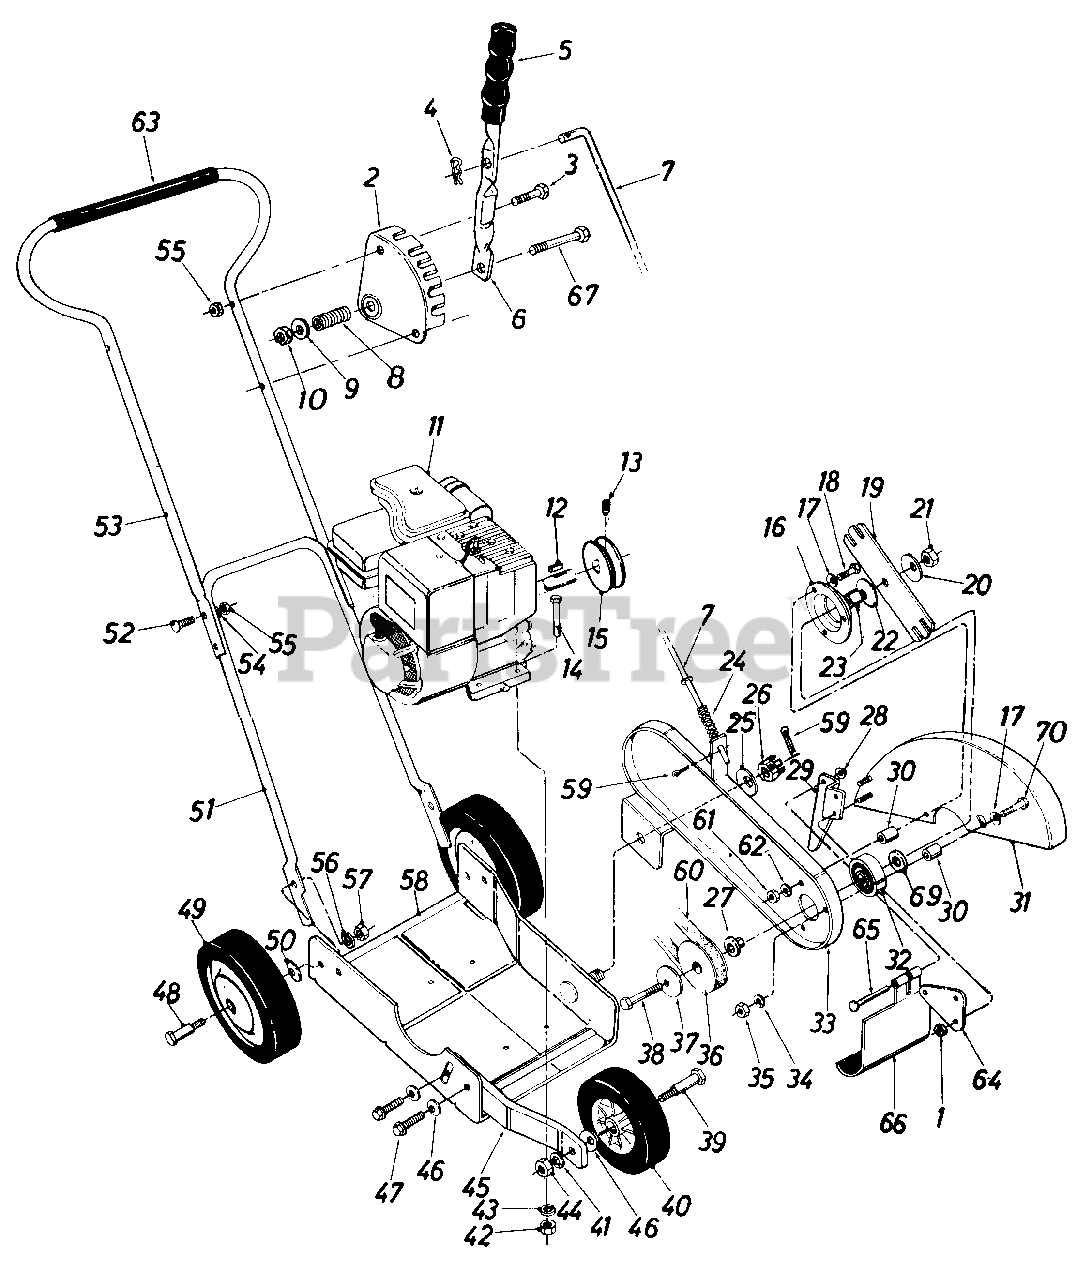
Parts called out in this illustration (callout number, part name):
1	Hex Cent. L. Nut 1/4-20 Thd .
3	Hex Bolt 1/4-20 x 1.25" Lg.
4	Cotter Pin 1/8" Dia. x 1.0" Lg.
5	Grip
7	Clutch Rod
8	Compression Spring.50" O.D. x 1.38" Lg.
9	Fl.-Wash. .34" I.D. x .62" O.D. x.063
10	Hex Cent. L.-Nut 5/16-18 Thd.
11	Engine
12	Sq. Key 3/16 x 1.0" Lg.
13	Set Scr. 1/4-28 x 1/4" Lg.
14	Hex Bolt 5/16-18x 1.50' Lg.
15	Engine Pulley
16	Bearing Housing
17	Bell.-Wash. .34" I.D. x 88" O.D. x .060
18	Hex Bolt 5/16-18 x 1.25" Lg.
20	Bell.-Wash. .535" I.D. x 1.50" O.D. x.052
21	Hex Cent. L.-Nut 1/2-20 Thd.
22	Bell.-Wash. .535" I.D. x 1.50" O.D. x .052
23	Spacer
24	Compression Spring .57" O.D. x 1.92" Lg.
25	Bell.-Wash..535" I.D. x 1.50" O.D. x .052
26	Hex Castle Nut 1/2-20Thd.
27	Shoulder Spacer
28	Push Cap
29	Guide
30	Spacer.354" I.D. x .635" O.D. x .510" Lg.
33	Spindle Bracket Ass'y.
34	L.-Wash. 5/16" I.D.
35	Hex Nut 5/16-18 Thd.
36	Pulley
37	Bell.-Wash. .535" I.D. x 1.50" O.D. x.052
38	Hex Bolt 1/2-20 x 3.50" Lg.
39	Shoulder Bolt .498" Dia. x 1 .450
40	Wheel Ass'y. Comp. 6" Dia. x 1.50
41	L.-Wash. 3/8 " 1. D.
42	Hex Nut 5/16-18 Thd.
43	L.-Wash. 5/16" I.D.
44	Hex Nut 3/8-16 Thd.
45	Front Wheel Support
46	Bell.-Wash. .400" I.D. x 88" O.D. x.060
47	Hex Wash. Hd. Self Tap Scr. 3/8-1 6 x .75 " Lg.
48	Shoulder Bolt .498" Dia. x 1.450
49	Wheel Ass'y. Comp. 7" Dia. x 1.50
50	Bell.-Wash. .400" I.D. x 88" 0. D.
51	Lower Handle
52	Carriage Bolt 1/4-20 x 1.25" Lg.
53	Upper Handle
54	L.-Wash. 1/4" I.D.
55	Hex Nut 1/4-20 Thd.
56	L.-Wash. 3/8" I.D.
57	Hex Nut 3/8-16 Thd.
58	Base Ass'y.
59	Cotter Pin 1/8" Dia. x 1.0" Lg.
60	3V-Belt 31.2" Lg.
61	Hex Nut 5/16-18 Thd.
62	L.-Wash. 5/16" I.D.
63	Grip
64	Flap Bracket
65	Hinge Pin
66	Debris Deflector
67	Hex Bolt 5/16-18 x 1.75" Lg.
69	Fl.-Wash. .51 I.D. x 1.00 O.D. x.060
70	Hex Bolt 5/16-18 x 2.00" Lg.
